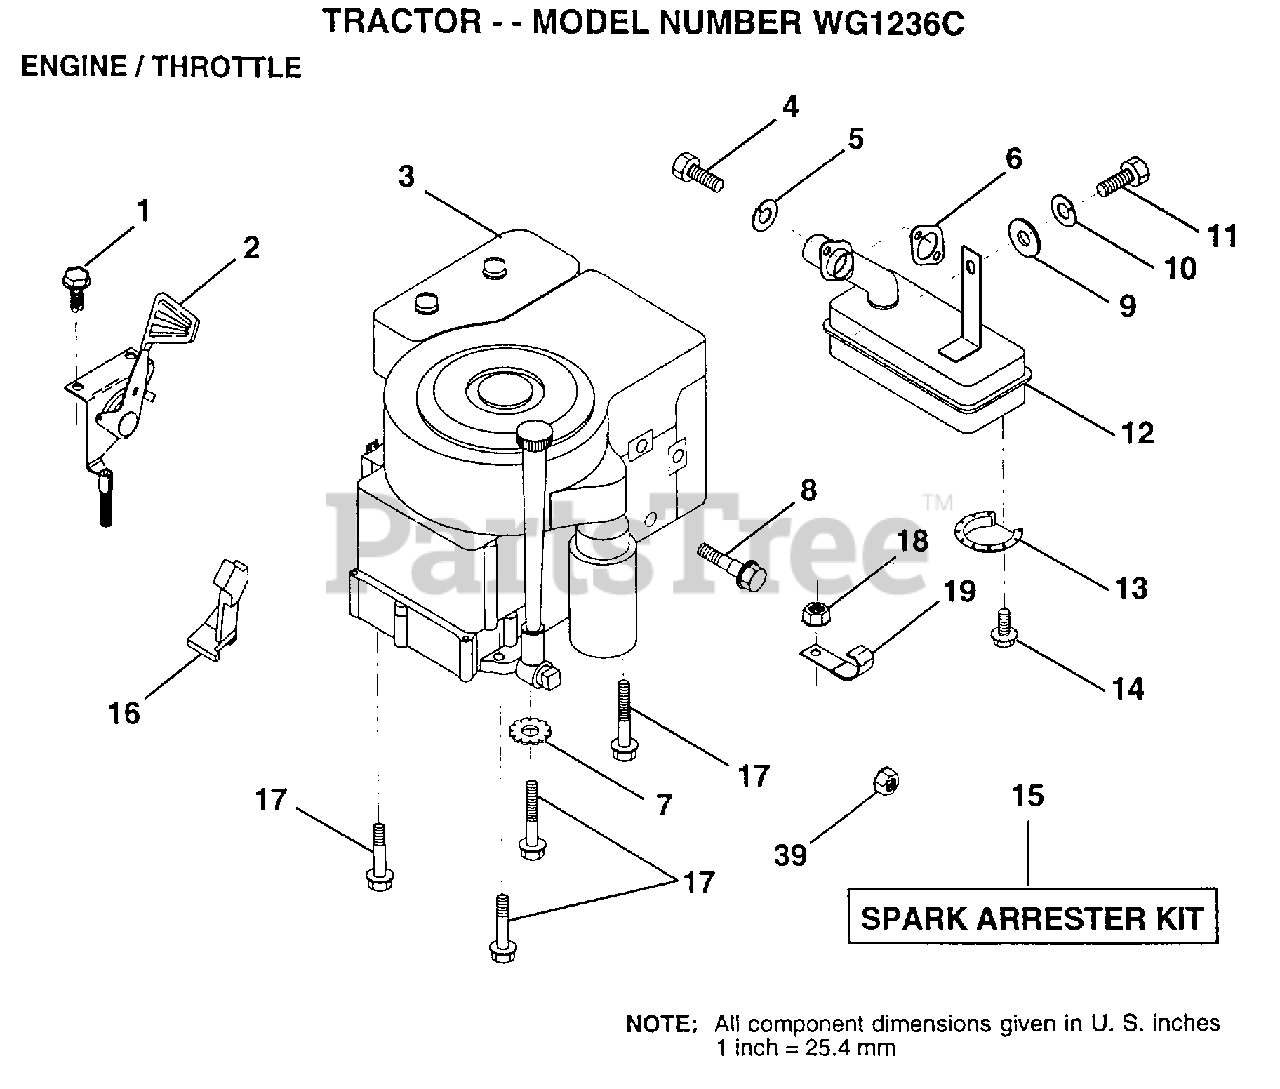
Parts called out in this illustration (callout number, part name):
1	SCREW.1/4-20X1/2
4	SCREW
5	LOCKWASHER
6	GASKET ENG 1 313 LD TIN PLATED
7	LOCKWASHER
8	BOLT T
10	LOCKWASHER
12	MUFFLER
13	DEFLECTOR.222573
16	"STOP,DASH THROTT"
17	SCREW LT
18	NUT
19	CLIP T
39	NUT
